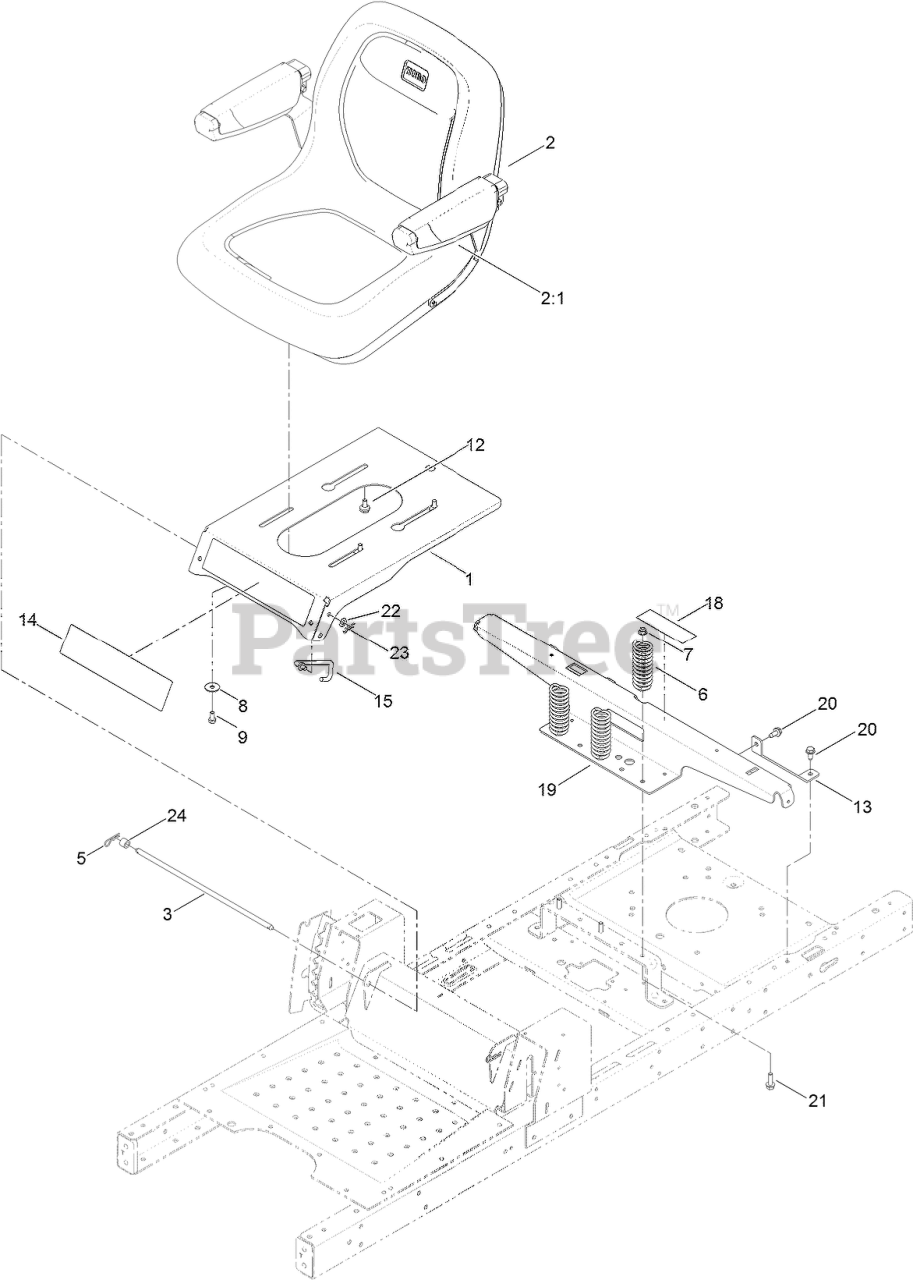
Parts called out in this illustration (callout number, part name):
1	PAN-SEAT
2	SEAT-18 Inch
2:1	ARMREST KIT (MILSCO)
3	ROD-STOP
5	PIN-COTTER
6	SPRING-COMPRESSION
7	NUT-HF, NI
8	WASHER-PIVOT
9	SCREW-HH
12	BOLT-SHOULDER
13	SUPPORT-TANK, REAR
14	DECAL-TIMECUTTER
15	STOP-SEAT
18	DECAL-SERVICE, CE
19	SUPPORT-POD, WIDE
20	SCREW-HWHTF
21	SCREW-HHF
22	WASHER-PLAIN
23	PIN-COTTER
24	BUSHING-LEVER, LIFT
